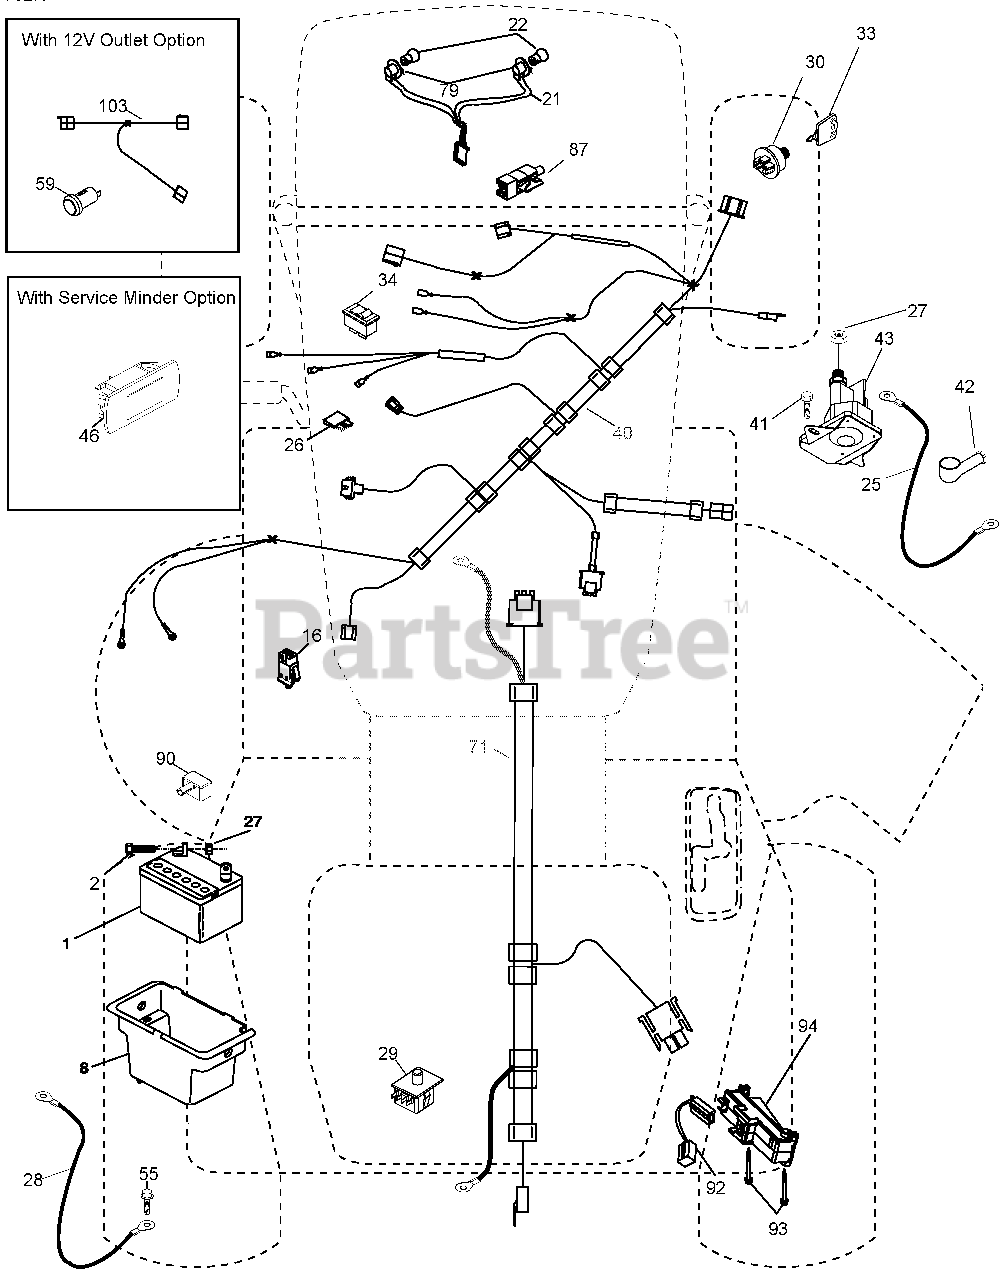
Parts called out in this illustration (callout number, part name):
1	BATTERY.12.VOLT.28.AMP.WET
2	BOLT.HEX.HD.1/4-20UNC X 3/4
8	BOX.BATTERY.MNT.REAR.LT.TEX.BL
16	SWITCH.INTERLOCK.NONO.GRAY
21	HARNESS ASM.LIGHT.22"(4152J)
22	HARNESS ASM.LIGHT.22"(4152J)
25	CABLE.STARTER.6GA.BL/RED.14.5"
26	FUSE.20 AMP.
27	Nut, Keps Hex 1/4-20 unc
28	CABLE.BLACK.22"REAR BATT.TEX
29	SWITCH.SEAT.DP.W/ROS
30	SWITCH.IGN.DLTA.P-IN.ROS
33	KEY/CHAIN.BLISTER PACK.GEN.CE
34	SWITCH.LIGHT/RESET.B/B/RED.
40	HARNESS.IGN.DASH.CBL.YTGT.PRED
41	Screw 1/4-20 x 1/2
42	COVER.TERMINAL.RED
43	SOLENOID.W/BRASS PLUNGER.2005
55	SCREW.5/16-18X3/4.SMGML.TAP/R
71	HARNESS.IGN.CHASS.TEX.REAR.BAT
79	SOCKET ASM.BULB.TWISTLOCK
87	SWITCH.INTRLCK.CLUTCH.CABLE.TX
90	COVER.TERMINAL.BATTERY.RR.TEX
92	HARNESS.PIGTAIL.CONSLE.ROS.MLK
93	SCREW.PLASTITE.10-14 X 2.0
94	MODUAL REVERSE ROS
